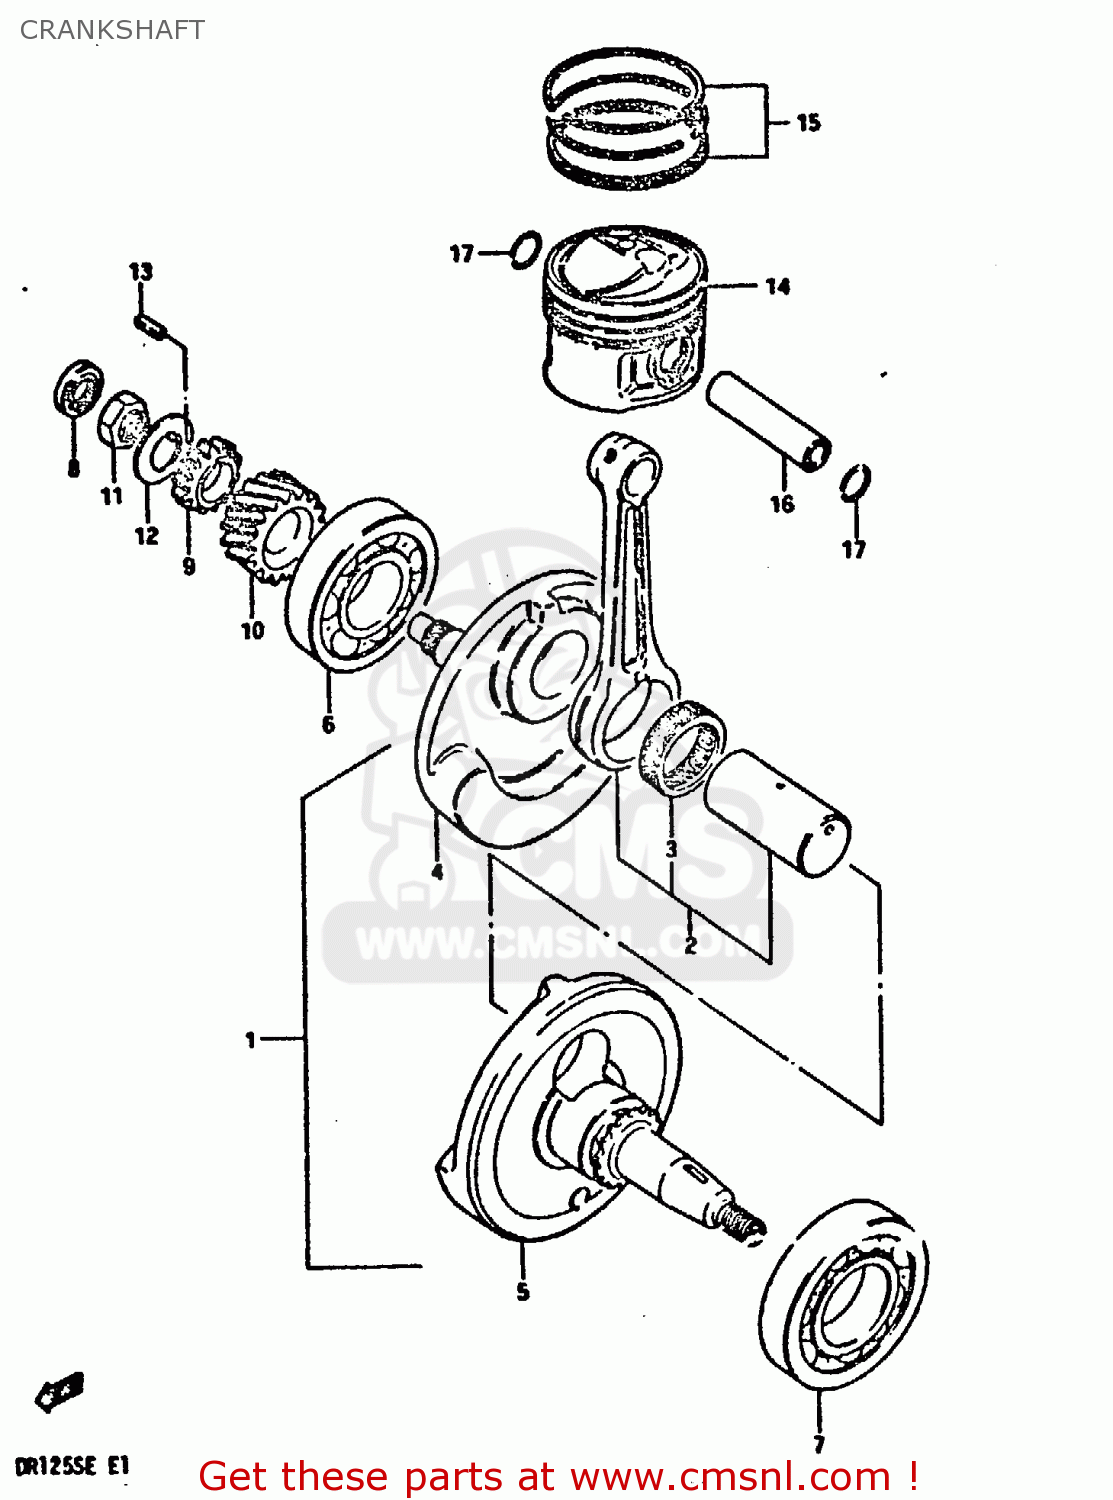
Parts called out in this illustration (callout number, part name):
1	CRANKSHAFT ASSEMBLY
2	CRANKSHAFT ASSEMBLY
3	BEARING
4	CRANKSHAFT
5	CRANKSHAFT,LEFT
6	BEARING,MIDDLE
7	BEARING,LEFT
8	OIL SEAL
9	GEAR,OIL PUMP DRIVE
10	GEAR,PRIMARY DRIVE
11	NUT
12	WASHER
13	KEY
14	PISTON (STD)
15	RING SET,PISTON
16	PIN,PISTON
17	RING,SNAP 14MM
